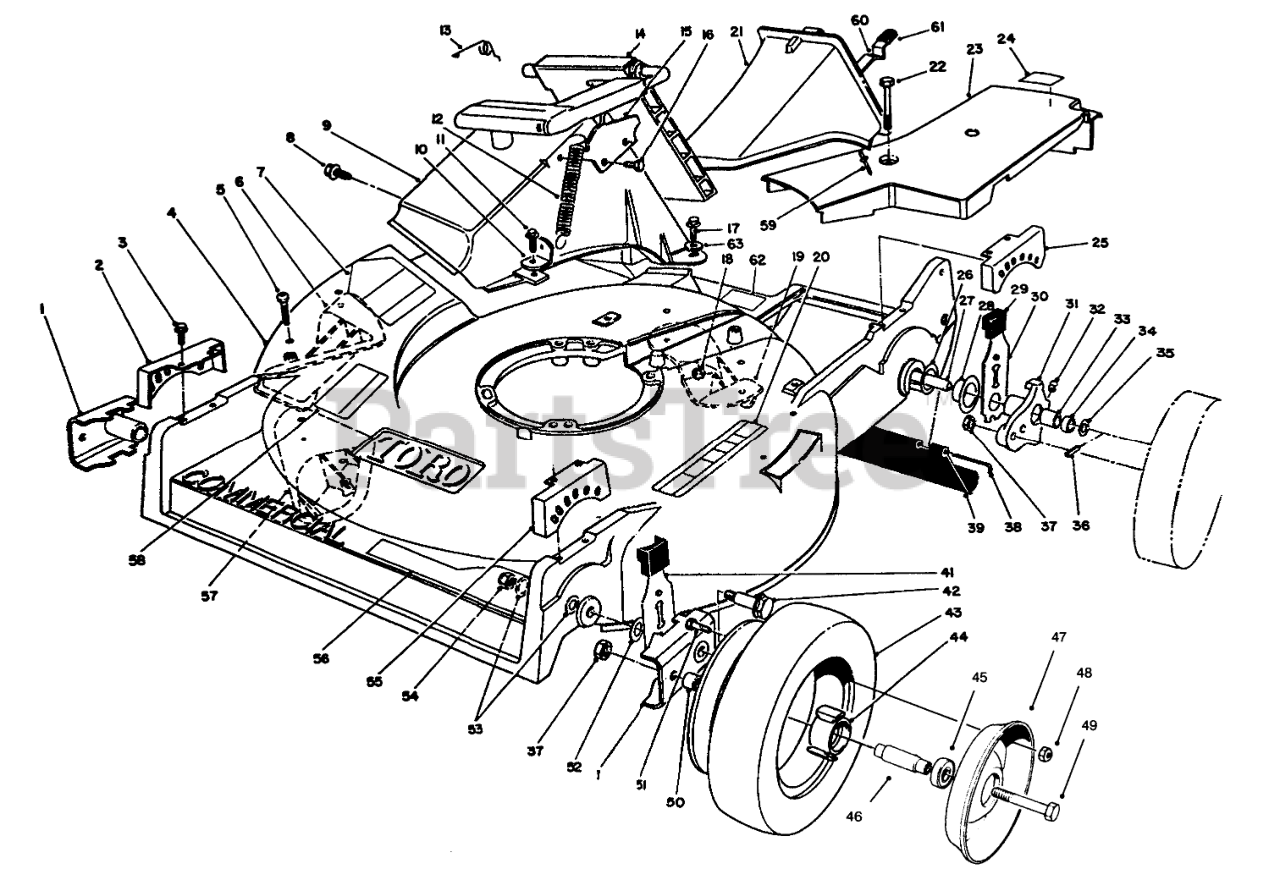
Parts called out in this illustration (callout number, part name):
1	ARM-PIVOT, FRONT
2	QUADRANT-FRONT, RH
3	SCREW-HWHTF
4	Housing (Incl. Ref.# 5-7,19, 20, 57, 58 & 62)
5	SCREW-HWHTF
6	KICKER-RH
7	DECAL-DANGER
8	SCREW AND WASHER ASM
9	DISCHARGE TUNNEL
10	BRACKET-SPRING
11	SCREW-HWH
12	SPRING-DOOR
13	RETAINER-DOOR
14	DOOR ASSEMBLY
15	DOOR LATCH PLATE
16	SCREW-PLASTITE
17	SCREW-HH
18	NUT-LOCK, NI
19	KICKER-REAR
20	DECAL-INSTRUCTION, SAFETY
21	DISCHARGE PLUG ASM
22	SCREW-HHFTF
23	BELT COVER (MACHINED)
24	LABEL-GREASE, HP
25	QUADRANT-REAR, LH
26	WASHER
27	SHAFT-AXLE, REAR
28	CAP-END
29	KNOB-ARM
30	REAR SPRING ARM ASM
31	Arm-Pivot (Incl. Ref. #32-34)
32	FITTING-GREASE
33	BUSHING
34	BUSHING
35	WASHER-PLAIN
36	PIN-SPIROL
37	NUT-LOCK, CONE
38	ROD-SHIELD
39	SHIELD-TRAILING
41	FRONT SPRING ARM ASM
42	BOLT-WHEEL
44	HUB-BEARING
45	BEARING-WHEEL
46	SPACER-BEARING
47	Wheel-Half
48	NUT-LOCK, NI
49	SCREW-HH
50	SPACER-WHEEL
51	SCREW-HH
52	WASHER-THRUST
53	WASHER
54	NUT-LOCK
55	QUADRANT-FRONT, LH
56	DECAL - RECYCLER
57	KICKER-FRONT
58	DECAL - DANGER, COVERS
59	RIVET-HEAD, FLAT
60	LATCH-PLUG, DISCHARGE
61	GRIP-LATCH
62	DECAL-WARNING
63	WASHER-FLAT
